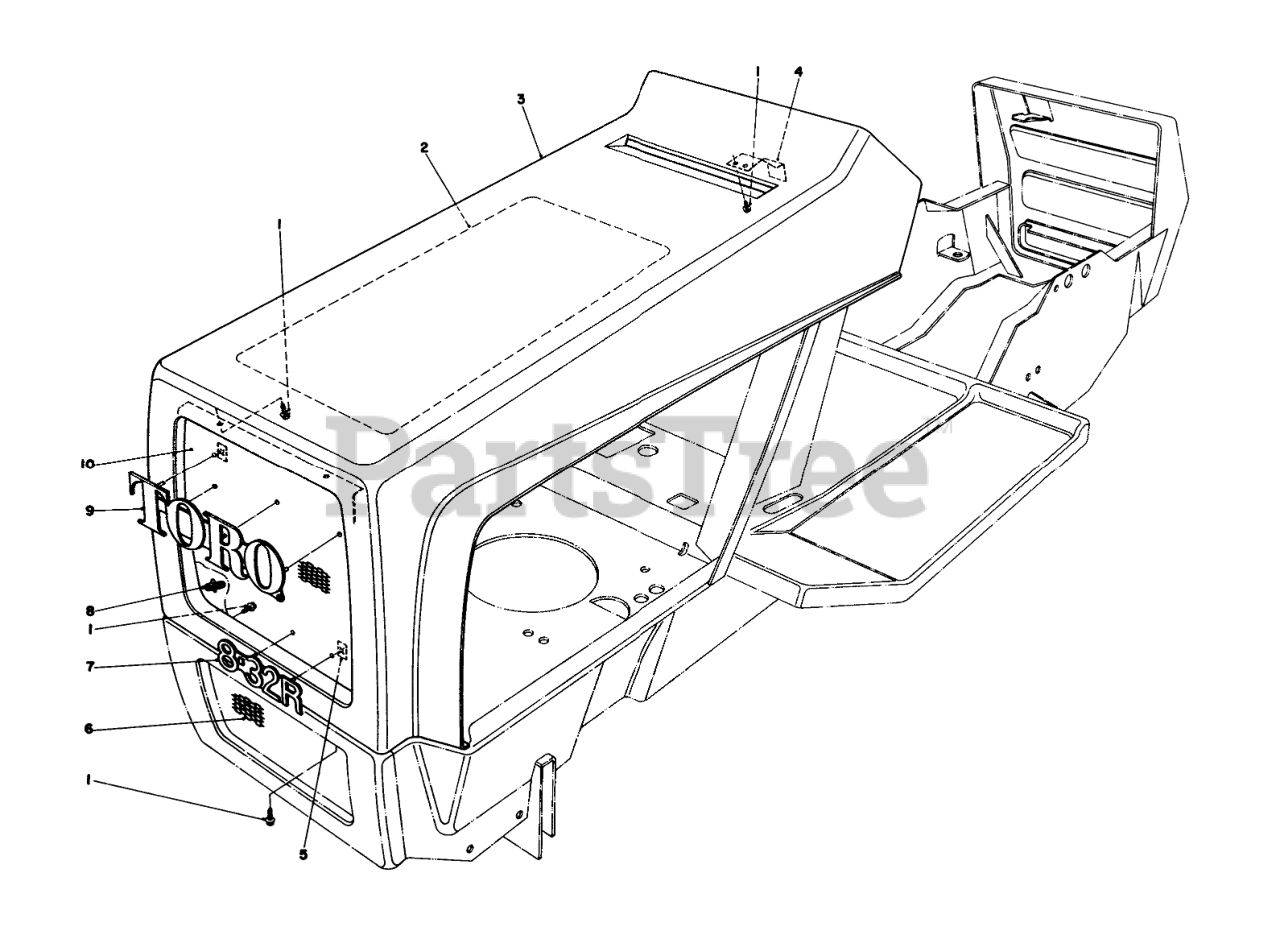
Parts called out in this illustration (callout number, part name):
1	SCREW-HWHTF
2	Decal-Service
3	Hood (Incl. Ref. #8)
4	SPRING LATCH
6	LOWER GRILLE
7	Name Plate Grille
8	HINGE BRKT STUD
9	Logo-Grille
10	Grille Hood
